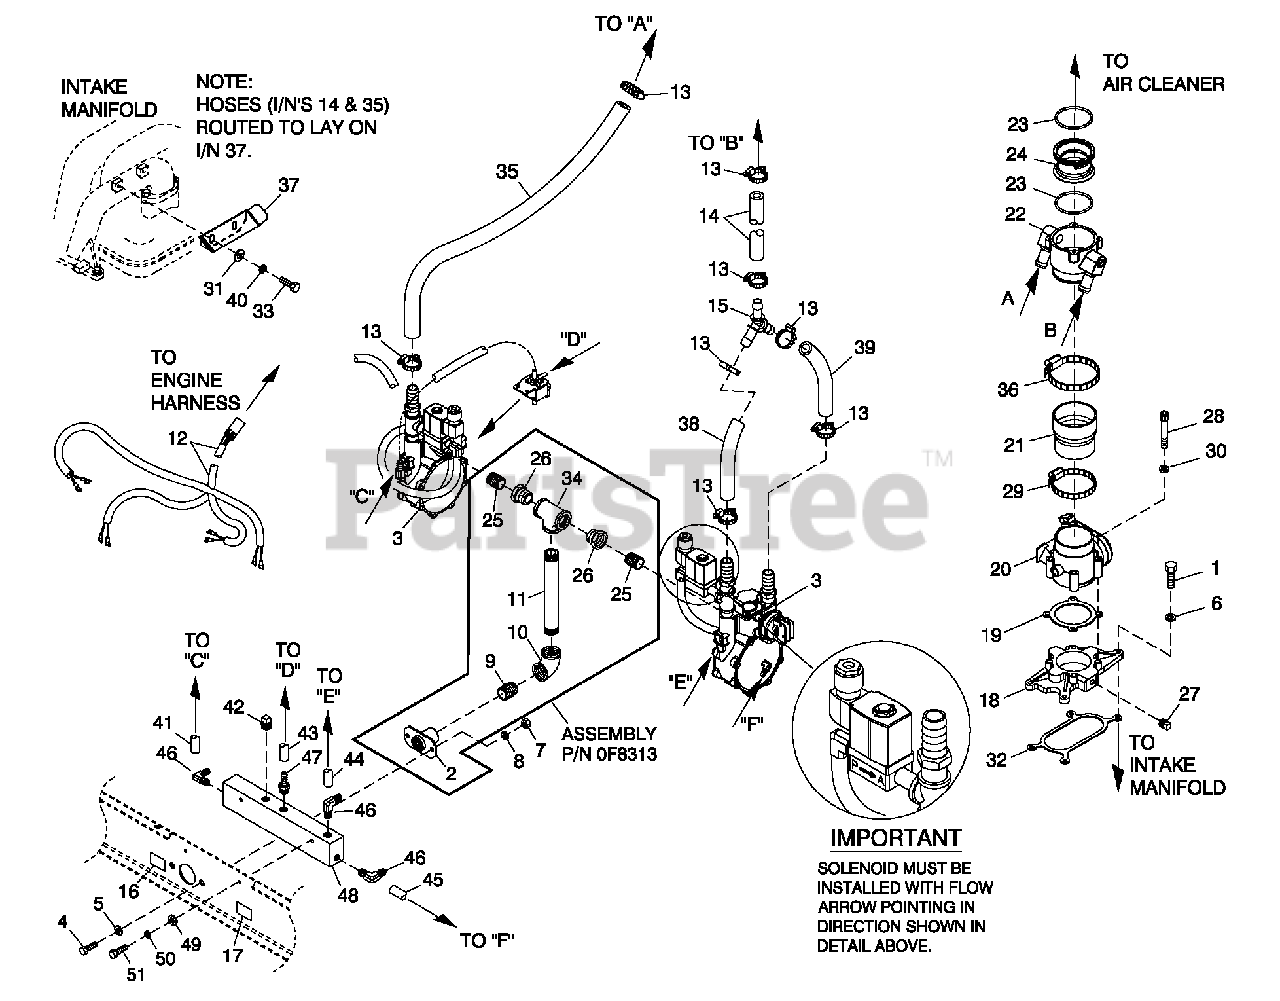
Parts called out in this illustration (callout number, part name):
1	SCREW HHC 5/16-18 X 1-1/4 G5
2	SUPPORT NAT GAS SOLENOID
3	REG 6.8L CPL 100 KW N/G EMISS
4	SCREW HHC M12-1.75 X 20 G8.8
5	WASHER FLAT 1/2 ZINC
6	WASHER LOCK M8-5/16
7	NUT HEX M12-1.75 G8 YEL CHR
8	WASHER LOCK 1/2
9	NIPPLE CLOSE 1.25 NPTX 1.625
10	ELBOW 90D1-1/4 NPT
11	NIPPLE PIPE 1-1/4 N PT X3
12	HARNESS, FUEL JUMPER DUAL REG
13	CLAMP HOSE #8 .53-1.00
14	HOSE 3/4 ID SAE-30R2 (42" LG)
15	Y CONNECTOR 500 SERIES BARBS
16	DECAL INLET PRESSURE
17	DECAL FUEL INLET NG
18	ADAPTOR THROTTLE BODY
19	GASKET GOVERNOR ACTUATOR
20	ACTUATOR BOSCH 60 GOVERNOR
21	REDUCER 3.0" TO 2.75" TURBO
22	MIXER 40/60MM ACTUATOR ASSY
23	O-RING 2-3/4X3/32X2-15/16
24	VENTURI, THROTTLE 42MM
25	NIPPLE CLOSE 3/4X1.375
26	BSHG RDCRHEX1-1/4-3/4
27	PLUG STD PIPE 1/4 STEEL SQ HD
28	SCREW SHC M6-1.0 X 50 C8.8
29	CLAMP HOSE #44 2.31-3.25
30	WASHER LOCK M6-1/4
31	WASHER FLAT M6
32	GASKET ADAPTER THROT BODY
33	SCREW HHC M6-1.0X 20 G8.8
34	PIPE TEE 1-1/4 NPT
35	HOSE 3/4 ID SAE-30R2 (45" LG)
36	CLAMP HOSE #52 2.81-3.75
37	BRACKET, HOSE RISER
38	HOSE 3/4 ID SAE-30R2 (9.5" LG)
39	HOSE 3/4 ID SAE-30R2 (12" LG)
40	WASHER LOCK M6-1/4
41	HOSE VACUUM 5/32 (5"LG)
42	PLUG STD PIPE 1/8 STEEL SQ HD
43	HOSE VACUUM 5/32 (18"LG)
44	HOSE VACUUM 5/32 (6"LG)
45	HOSE VACUUM 5/32 (8"LG)
46	BARBED EL 90 3/16X1/8
47	BARBED STR 1/8NPTX 3/16
48	MANIFOLD, EMISSIONS VACUUM
49	WASHER FLAT 1/4-M6 ZINC
50	WASHER LOCK M6-1/4
51	SCREW HHC M6-1.0X 25 G8.8
